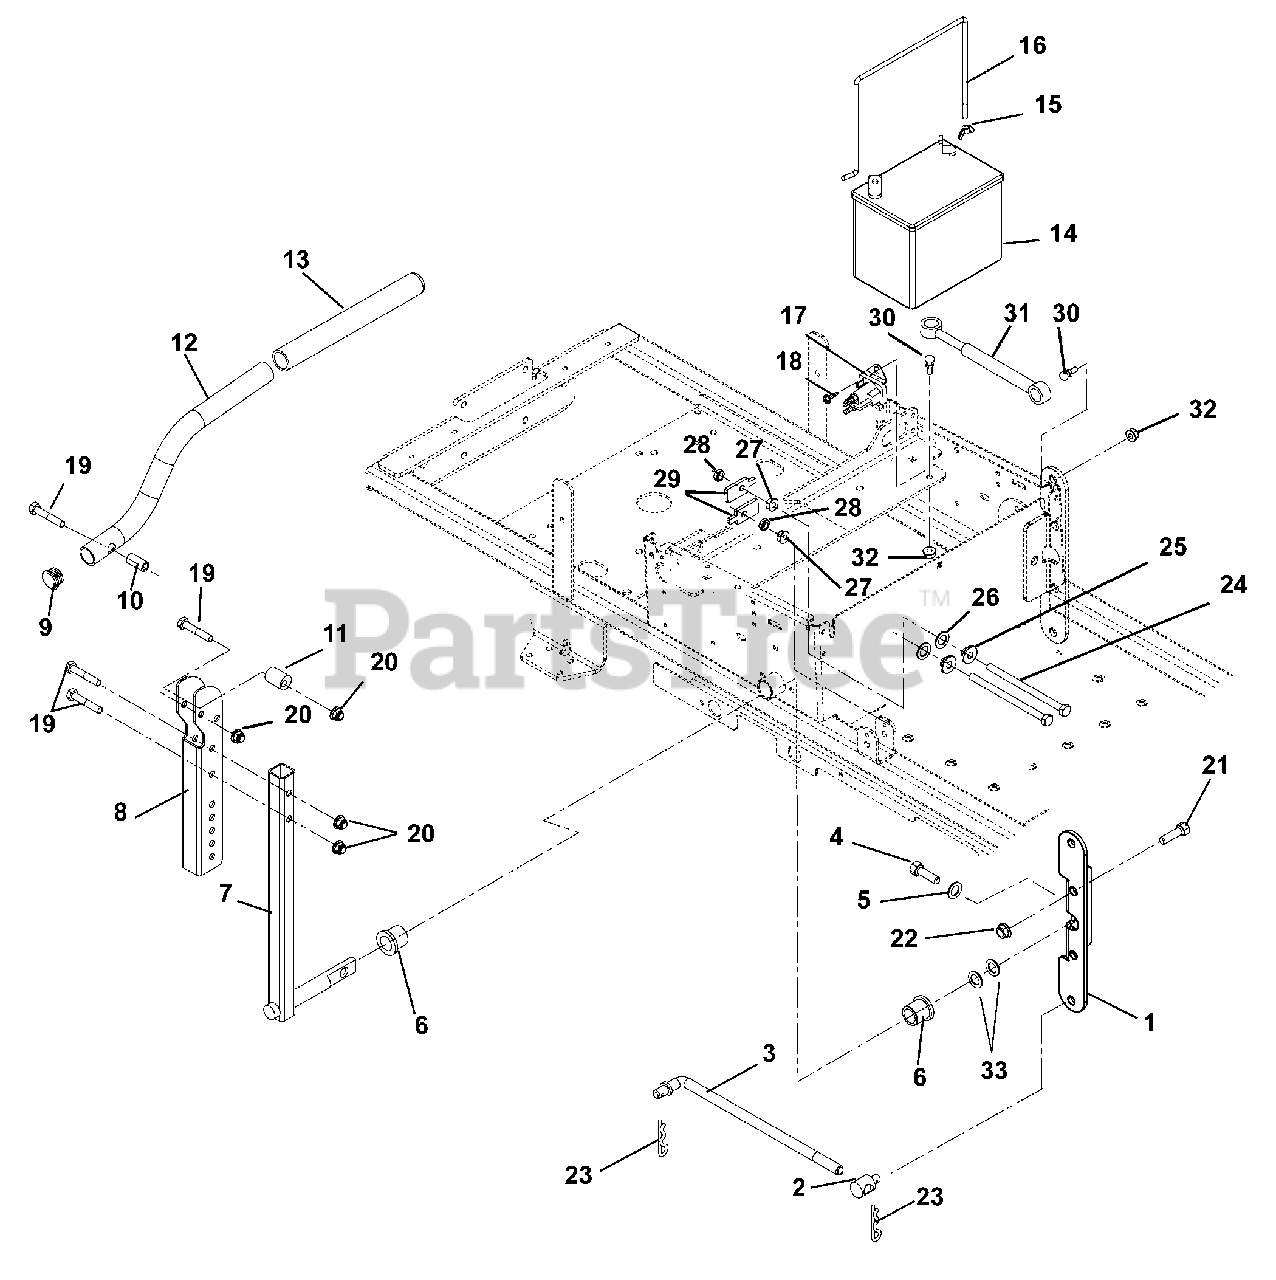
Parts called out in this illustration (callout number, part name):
1	Weldment, Control Link
2	Pivot, Rod
3	Link, Wireform
4	Bolt, .38-16 x 1 Grade 8 EP30
5	Washer, Flat Steel .390 x 1.5 x .125
6	Bushing, 1.00 x .75 x 1.00
7	Weldment, Control Arm
8	Channel, Upper Handlebar
9	Caplug, Handlebar
11	Eccentric
12	Handlebar
13	Grip, Handlebar
15	Nut, Lock Wing .250-20
16	Battery Rod
17	Solenoid
18	Screw, Tap .250-20 x .37
19	Bolt, Hex .31-18 x 1.75 Grade 5
20	Nut, 5/16-18 Flange Nyloc
21	Bolt, Hex .38-16 x 1.25 Grade 5
22	Nut, Hex Jam .375-16
23	Pin, Hair Internal .08 x .18 x 1.18
24	Bolt, Hex 5/16-18 x 5 Grade 2
25	Bushing, Flange .312 x .500 x .344 x .880
26	Washer, Flat Steel .52 x .827 x .062
27	Nut, Spin Lock-Flange .312-18
28	Nut, Jam .312-18
29	Stop Tab
30	Stud, Ball
31	Damper, Control
32	Nut, Locking Top Flange .31-18
33	Washer, Flat Steel .755 x 1.25 x .125
